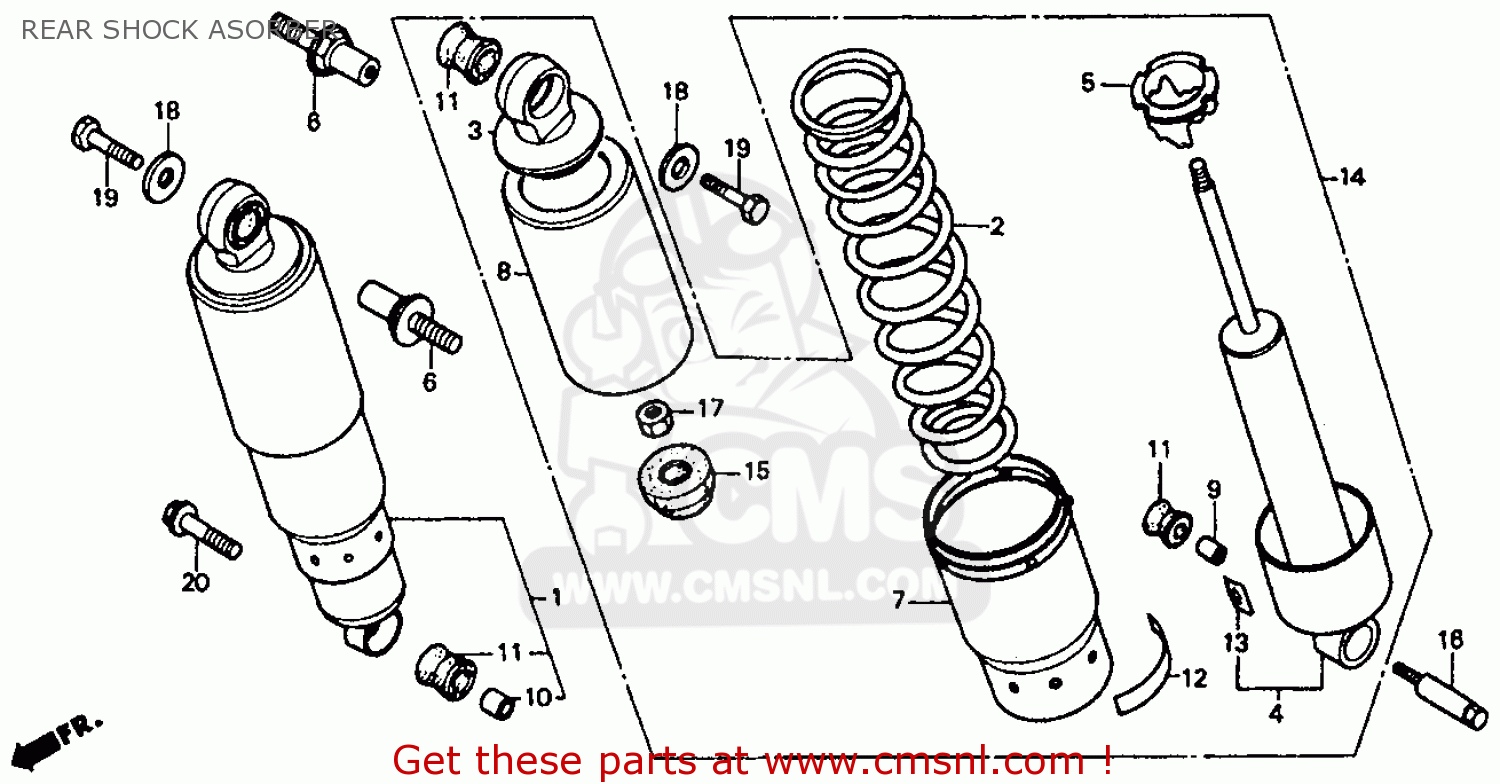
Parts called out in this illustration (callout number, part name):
1	CUSH ASSY,R RR
2	SPRING,RR.CUSHION
3	JOINT COMP,UPPER
4	DAMPER COMP.,RR.(
5	ADJUSTER,SPRING (
6	BOLT,RR.CUSHION
7	SEAL,SPRING
8	CASE,RR CUSH UP
9	COLLAR RR CUSH
10	COLLAR,RR.CUSHION
11	BUSH,REAR CUSHION
12	LABEL A
13	LABEL B,RR.CUSH.
14	CUSH ASSY,L RR
15	RUBBER,STOPPER
16	BOLT,RR CUSHION
17	NUT,HEX.,11MM
18	WASHER,8.5X26
19	BOLT,HEX,8X12
20	BOLT,FLANGE,10X35
